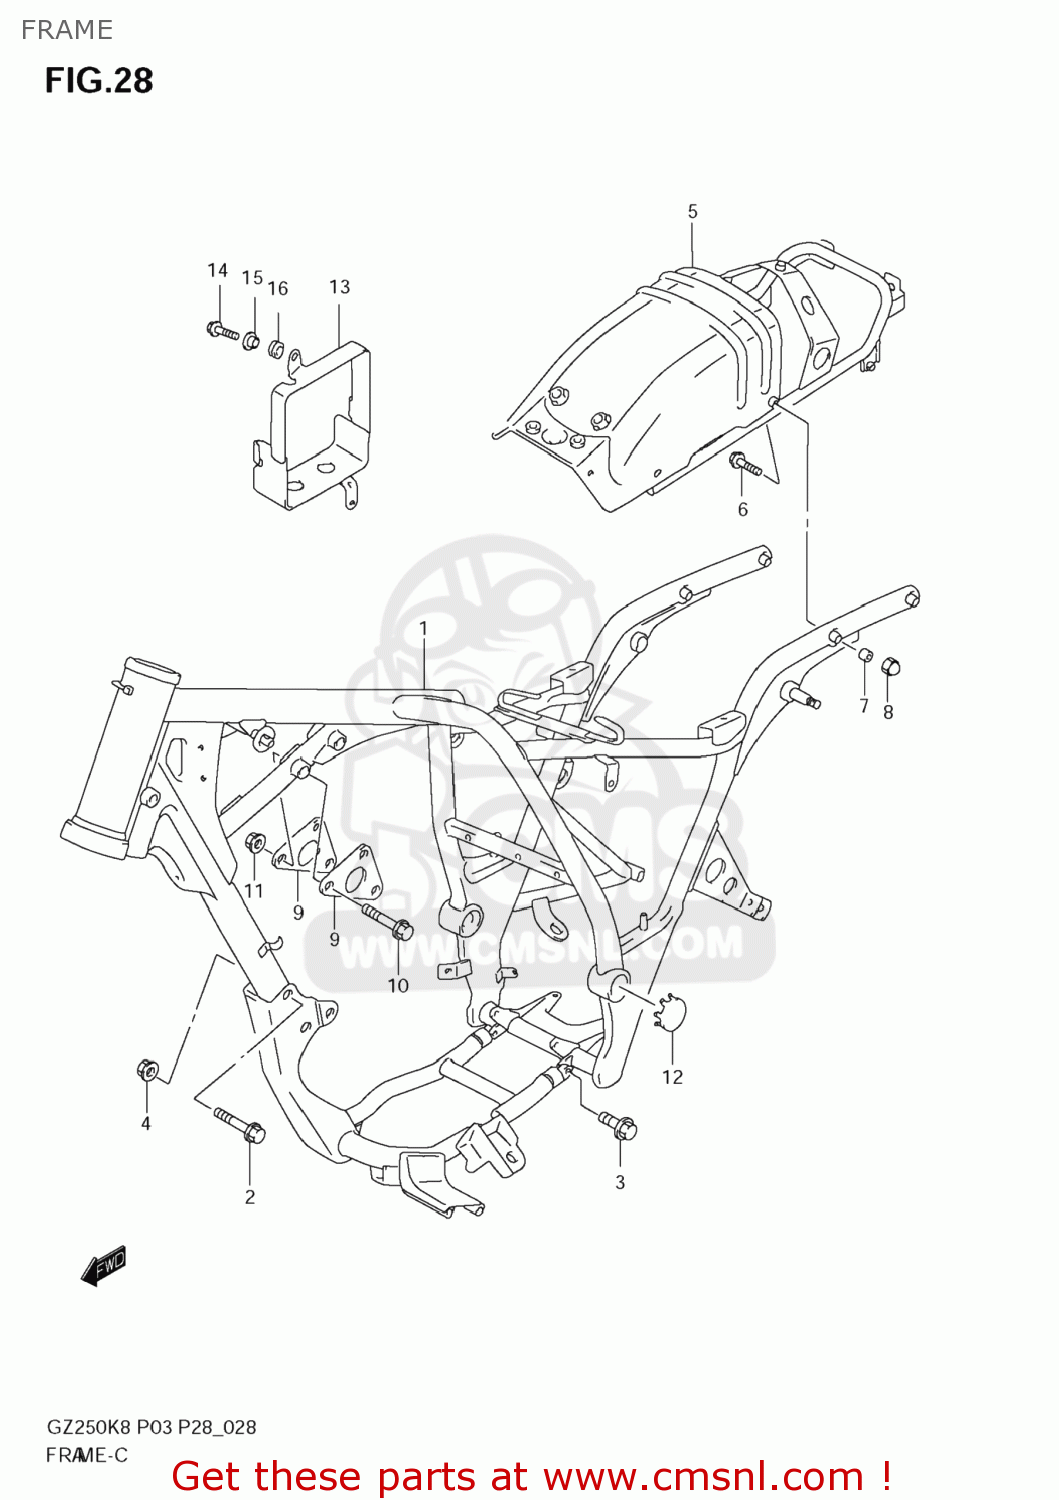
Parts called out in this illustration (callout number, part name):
1	FRAME (BLACK)
2	BOLT
3	BOLT
4	NUT
5	BRACE,REAR FR.
6	BOLT
7	SPACER(8.5X16X10)
8	NUT
9	PLATE ENGINE M
10	BOLT(8X50)
11	NUT
12	CAP,RR SWINGING ARM PIVOT,R
13	HOLDER COMP. B
14	BOLT
15	WASHER
16	CUSHION
